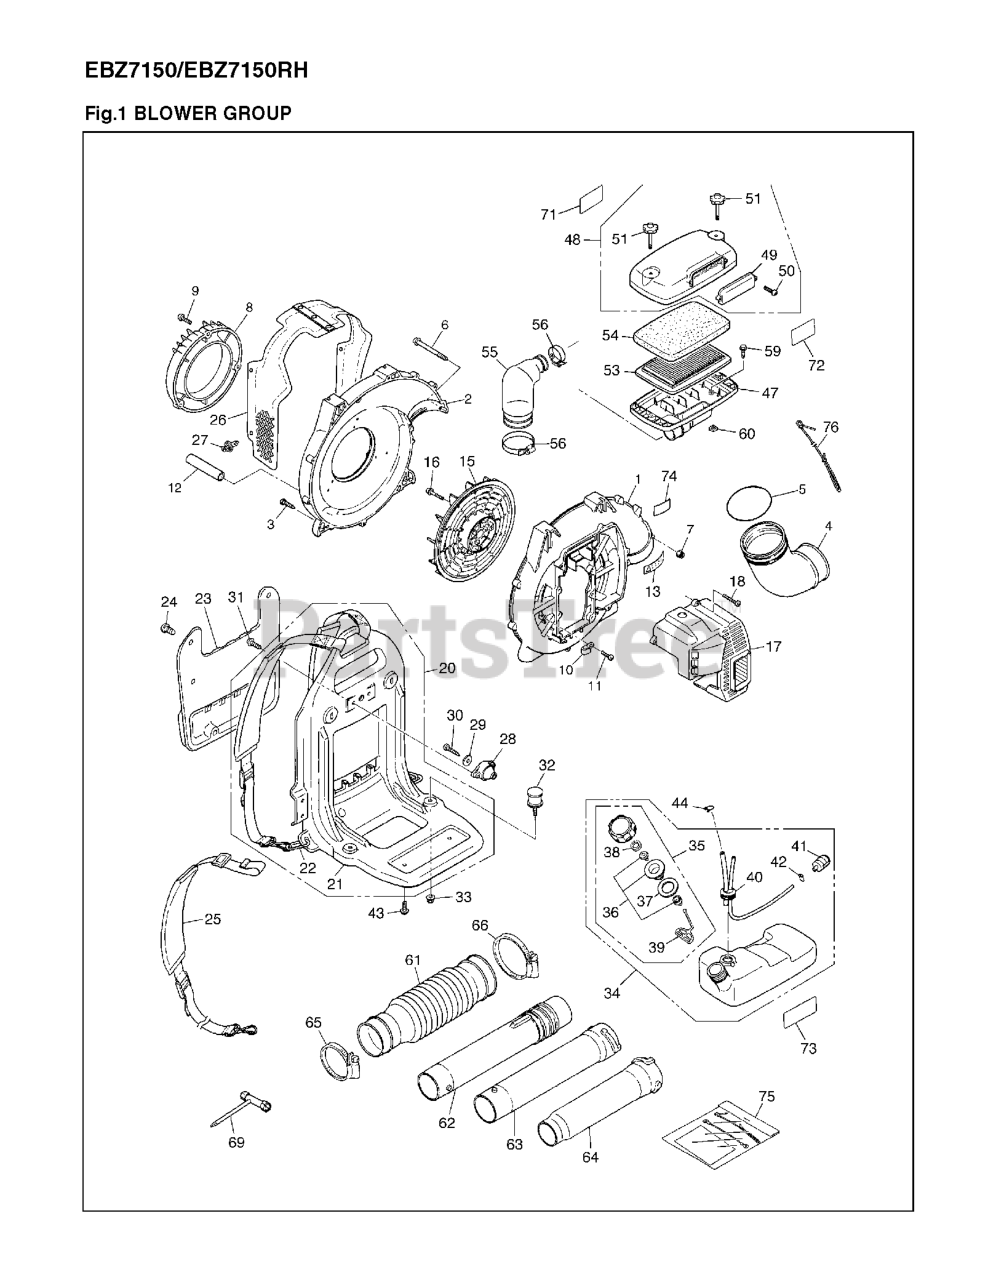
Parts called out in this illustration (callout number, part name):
1	VOLUTE CASE
2	VOLUTE COVER(R-848L5C55B3,B4)
4	ELBOW
8	COVER, INLETEB7001
12	TUBE
13	LABEL,CAUTION
15	FAN
16	BOLT
17	ENGINE COVER
20	FRAME ASSY(RPLS -3500,-3501)
21	FRAME COMP.
22	RING
24	CLIP (RPLS 3490-21320)
25	BAND ASSY. (BUCKLE 275632910)
26	NET COMP (RPLS-T402325430)
27	CLIP
28	DAMPER UPPER
29	WASHER
30	BOLT
31	SCREW
32	DAMPER
34	TANK ASSY FOR EBZ7150
35	ASSY FUEL CAP
36	HOLDER-A
40	PIPE COMPLETE
41	FILTER ASSY
42	CLIP
43	SCREW
44	CLIP
47	BODY CLEANER
48	COVER ASSY
51	KNOB BOLT
53	ELEMENT
54	ELEMENT
56	CLAMP(F64)
59	BOLT
62	SWIVEL JOINT
64	PIPE, END (RPLS 848L5C65E0)
65	CLAMP(F96)
66	CLAMP(F115)
69	SOCKET
72	LABEL CLEANER 848L6H90R0
75	CABLE KIT
76	CORD, ANTISTATIC
